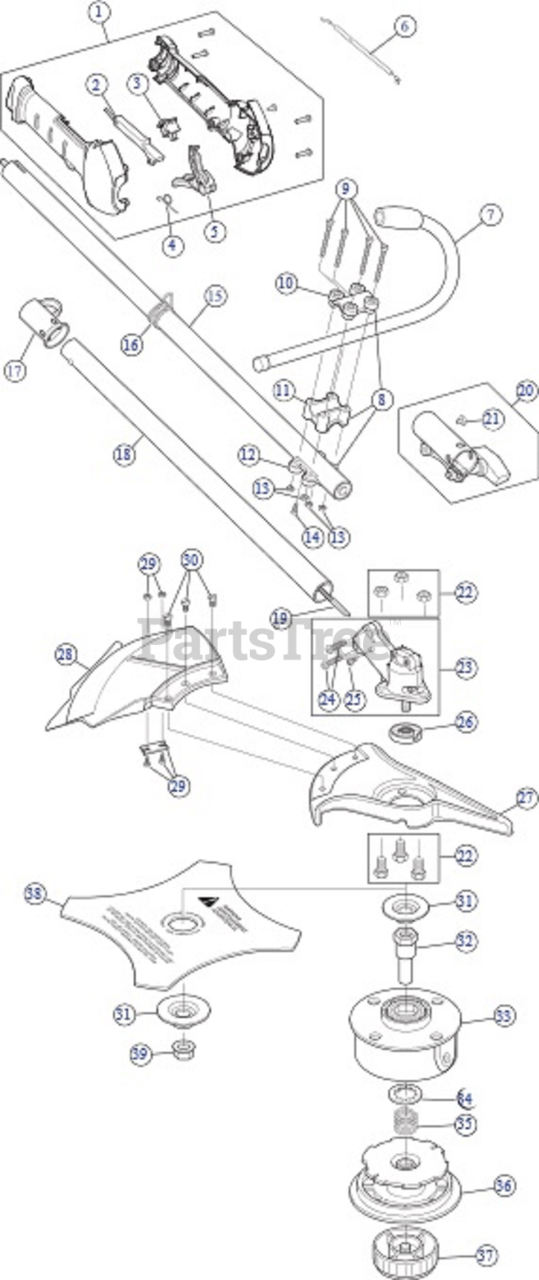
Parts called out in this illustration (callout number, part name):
1	Throttle Housing Assembly
2	Throttle Trigger Lock-Out
3	Switch Assembly
4	Throttle Trigger Spring
5	Throttle Trigger
6	Throttle Cable Assembly
7	J-Handle Assembly
8	J-Handle Bracket Assembly
10	Upper Handle Clamp
11	Middle Handle Clamp
12	Lower Handle Clamp
14	Anti-Rotation Screw
15	Upper Drive Shaft Housing Assembly
16	Harness Clip
18	Lower Drive Shaft Housing Assembly
19	Lower Flexible Drive Shaft
20	Split Boom Coupler
22	Shield Mount Screw Assembly
23	2 Piece Gearbox Assembly
24	Gearbox Mounting Hardware
25	Anti-Rotation Screw
26	Blade Driver
27	Blade Shield / Shield Mount
28	Shield Assembly
29	Blade Assembly
30	Shield Mounting Screw
31	Retaining Washer
32	Spool Shaft
33	Outer Spool Assembly
34	Retainer
37	Bump Head Knob Assembly
38	4-Tooth Blade
